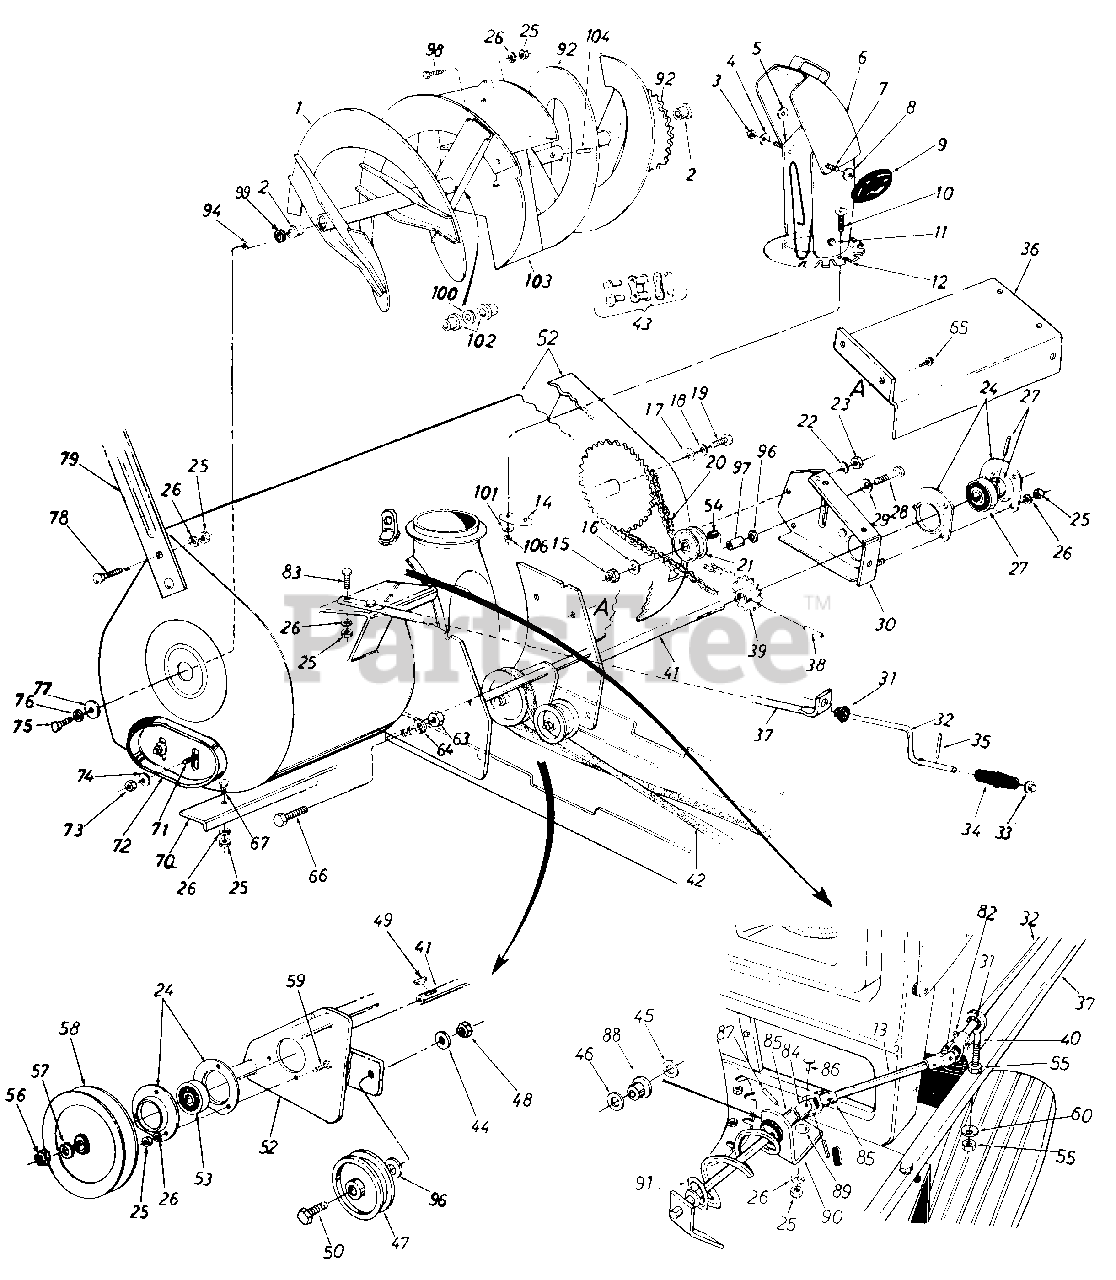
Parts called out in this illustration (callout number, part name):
3	Hex Cent. L.-Nut 5/16-18 Thd.
4	Belleville Wash. 3/8" I.D.
5	Flat Washer 3/8" I.D.
6	Top Chute Ass'y.
7	Carriage Bolt 5/16-18 x .62" Lg.
8	Belleville Washs. 3/8" I.D.
9	Hand Knob
10	Truss Mach. Scr 1/4 20 x .75"Lg.
11	Push Cap .188" Dia. Rod
12	Chute Ass'y.
13	Chute Crank Extension Rod
14	Chute Flange Keeper
15	L.-Nut 3/8-16 Thd.
16	Fl.-Wash.
17	Fl.-Wash.
18	Belleville Wash.
19	Hex Bolt 1/2-13 x 1.00" Lg.
20	#420 Chain 1/2" Pitch x 77 Links
21	Plastic Idler 2.00" O.D.
22	L.-Wash. 1/4" I.D.
23	Hex Nut 1/4-20 Thd.
24	Bearing Housing
25	Hex Nut 5/16-18 Thd.
26	L.-Wash. 5/16" I.D.
27	Self-Aligning Bearing
28	Hex Bolt 3/8-16 x 1.75"Lg.
29	Belleville Wash. 3/8" I.D.
30	Chain Guard Ass'y.
31	Nylon Bushing
32	Chute Crank .375 Dia. x 33"Lg.
33	Push Nut 3/8" Rod
34	Knob (Black)
35	Roll Pin
36	Drive Shaft Cover
39	14 Teeth Sprocket Ass'y.
40	Eyebolt 5/16-18 x 3.0" Lg.
41	Drive Shaft
42	"V"Belt 1/2" x 88" Lg. Kevlar
43	Master Link for #420 Chain
44	L.-Wash. 3/8" I.D.
45	Fl.-Wash. .385 I.D. x .62" O.D.
46	Fl.-Wash. .390 I.D. x 1.50" O.D.
47	Fl.-Idler with Flanges
48	Hex Jam L.-Nut 3/8-26 Thd.
49	#61 Hi-Pro Key
50	Hex Bolt 3/8-16 x 1.50" Lg.
52	Spiral Housing Ass'y.
53	Self-Aligning Bearing
54	Sleeve Bearing .50" I.D.
55	Hex Nut 5/16-18 Thd.
56	Hex Nut 3/4-10 Thd.
57	L.-Wash. 3/4" I.D.
58	"V"-Pulley .750" I.D. x 6.00" 0. D.
59	Hex Sems Bolt 5/16-18 x .75" Lg.
60	Bell.-Wash. .345" I.D. x .88" O.D.
63	Hex L.-Nut 1/2-20 Thd.
64	L.-Wash. 1/2"I.D.
65	Hex Wash. Hd. Tap Scr. 1/4-20 x .50" Lg.
66	Hex Bolt 1/2-20 x 1.25" Lg.
67	Carriage Bolt 5/16-18 x .62"
72	Skid Shoe
73	Hex Nut 3/8-16 Thd.
74	Belleville Wash. 3/8" I.D.
75	Hex Bolt 1/2-13 x 1.00" Lg.
76	Belleville Wash. 1/2" I.D.
77	Fl.-Wash.
78	Carriage Bolt 5/16-18 x .62"Lg.
79	Drift Cutter
82	Cotter Pin
83	Hex Bolt 5/16-18 x 1.50" Lg.
84	Joint Block
85	Joint Bracket Ass'y.
86	Oval Head Rivet
87	Spring Pin Roll 1/8" Dia. x .75" Lg.
88	Nylon Bushing
89	Carriage Bolt 5/16-18 x .62
90	Chute Crank Bracket
91	Chute Crank Ass'y.
96	Flat Washer
97	Idler Spacer
98	Carriage Bolt 5/16-18 x .75" Lg.
99	Fl.-Wash. 1.0" I.D. x 1.75" O.D.
100	Fl.-Wash. 1.03" I.D. x 1.62" O.D.
101	Bell. Wash. 1/4" I.D.
102	Plastic Bushing
106	Hex Nut 1/4-20 Thd.
